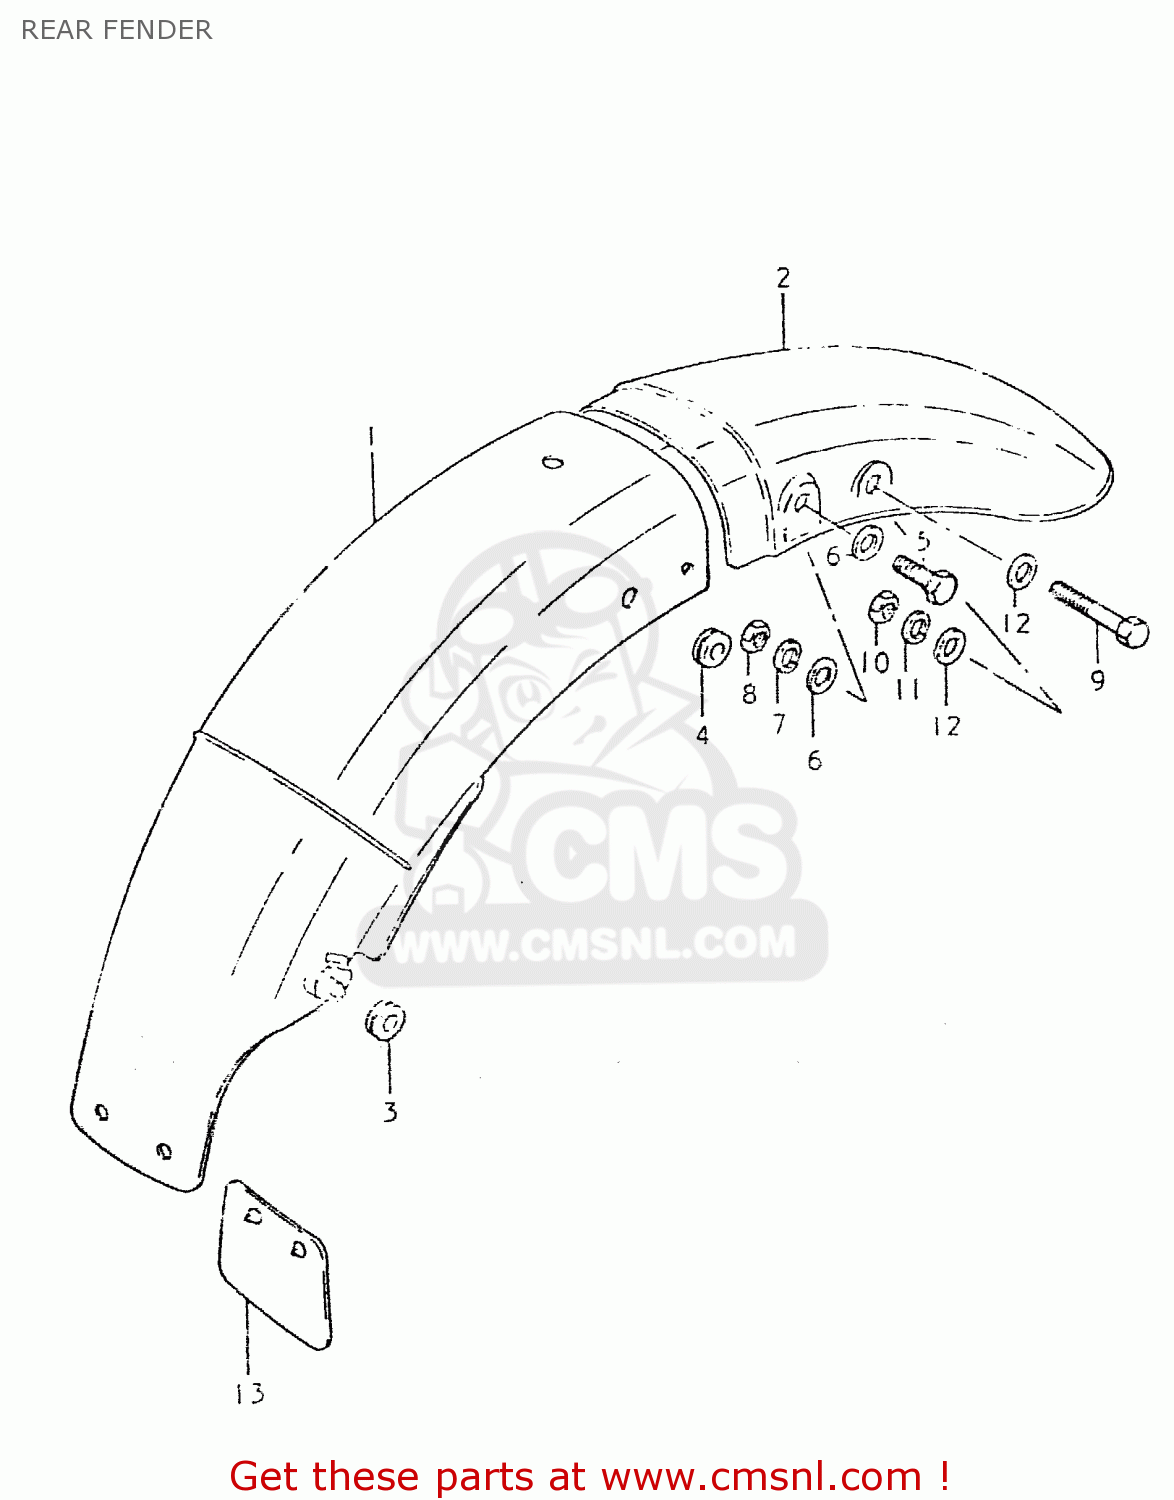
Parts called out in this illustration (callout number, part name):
1	FENDER,REAR
2	BODY, REAR FENDER REAR
3	CUSHION
4	CUSHION
5	BOLT
6	WASHER
7	LOCK WASHER
8	NUT
9	BOLT
10	NUT 8MM
11	LOCK WASHER
12	WASHER
13	GUIDE,RR FENDER MUD
